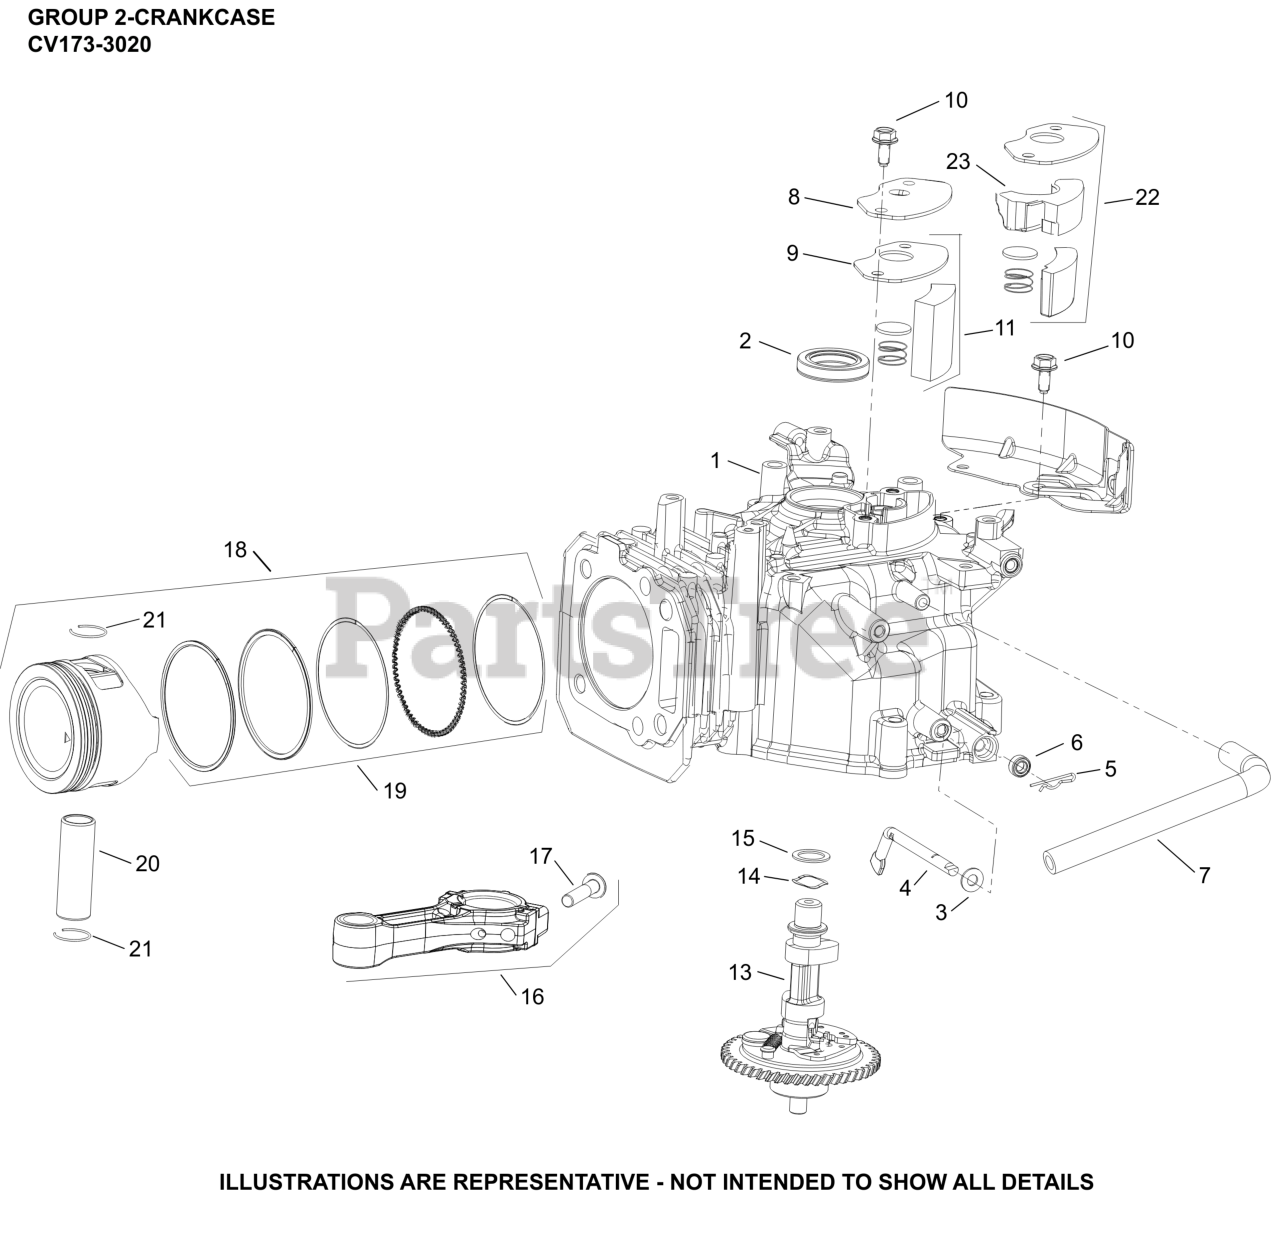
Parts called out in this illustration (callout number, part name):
1	CRANKCASE
2	SEAL, OIL
3	WASHER, FLAT (DIA 13mm O.D.)
4	SHAFT, GOVERNOR CROSS
5	CLIP, GOVERNOR SHAFT
6	SEAL, OIL
7	HOSE, BREATHER
8	COVER, BREATHER
9	GASKET, BREATHER COVER
10	SCREW, HEX FLANGE (M6)-USE 25 086 433-S
11	KIT, BREATHER FILTER
13	CAMSHAFT ASSEMBLY
14	SPRING, WAVE
15	WASHER, CAMSHAFT
16	CONNECTING ROD
17	SCREW, HEX FLANGE (M7)
18	KIT, PISTON
20	PIN, PISTON
21	RETAINER, PISTON PIN
22	KIT, BREATHER FILTER
23	FILTER, BREATHER MEDIA-USE 14 050 31-S
